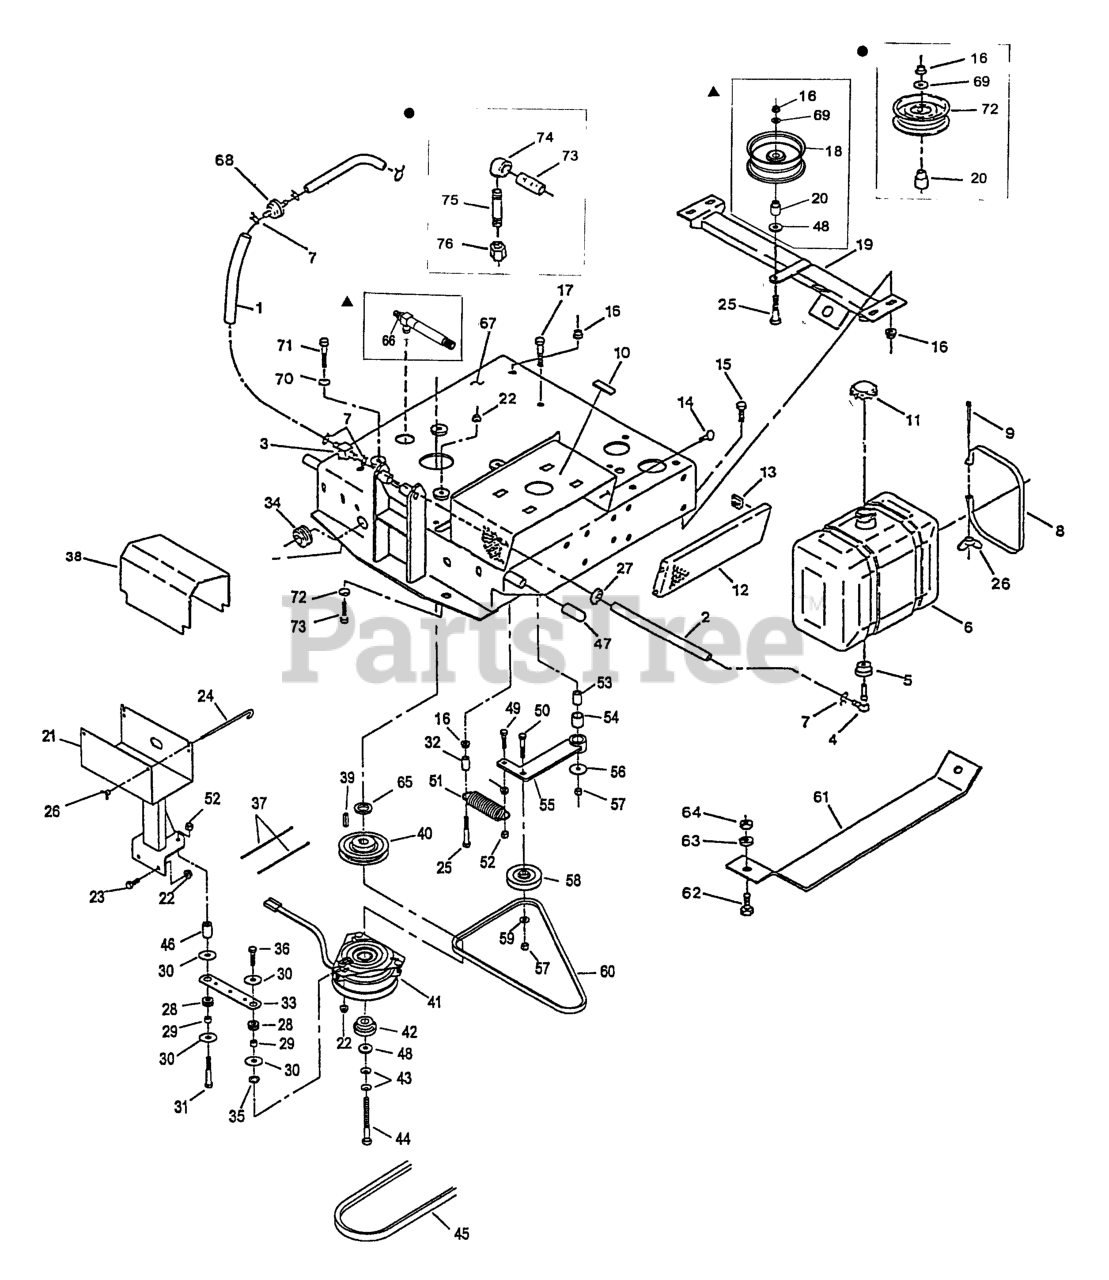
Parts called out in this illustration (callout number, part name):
1	HOSE-FUEL
3	VALVE-FUEL
4	ELBOW-TANK, FUEL
9	SCRW,MACH CRPH
10	PAD,PLASTIC TANK
11	CAP-FUEL
13	NUT,RETNR UTYP 1/4-20
14	SCREW,REGTHMB,
15	SCREW-HH
16	NUT-HHF, WHIZ
17	SCREW-HH
19	WLD,CROSSMEMBER
20	BUSHING,IDLER
21	WLD,BATTERY MOUNT
23	SCREW-HH
24	BOLT - HOLD DOWN
25	SCREW-HH
26	WINGNUT
27	GROMMET
28	GROMMET
31	SCREW-HH
33	STRAP-CLUTCH, BRAKE
34	GROMMET
35	WASHER-LOCK
36	SCREW-HH
37	TIE-PLASTIC
40	SHEAVE,4.25 OD A
42	BUSHING,CLUTCH KEEPER
43	WASHER-SPRING
44	SCREW-HH
45	BELT,DECK DRIVE
47	GRIP-LEVER, DRIVE
48	WASHER
49	Bolt-Carriage 5/16-18 X 1 1/4
50	SCREW-CARR
51	SPRING,EXTENSION
52	NUT-LOCK, NI
53	BUSHING,STEEL
54	BUSHING,IDLER ARM
55	WLD,IDLER ARM HYDRO
57	NUT-LOCK, NI
58	IDLER,PULLEY
59	WASHER-FLAT
60	BELT,A TRANS DRIVE
61	PLATE-SKID
62	SCREW-HH
63	WASHER-LOCK
64	NUT-HH
65	SPACER-CRANKSHAFT
66	VALVE-DRAIN, OIL
68	Fuel Filter
69	WASHER-FLAT
70	WASHER-SPRING
71	SCREW-HH
74	ELBOW-90 DEG
75	NIPPLE,PIPE
76	CAP-HEX
